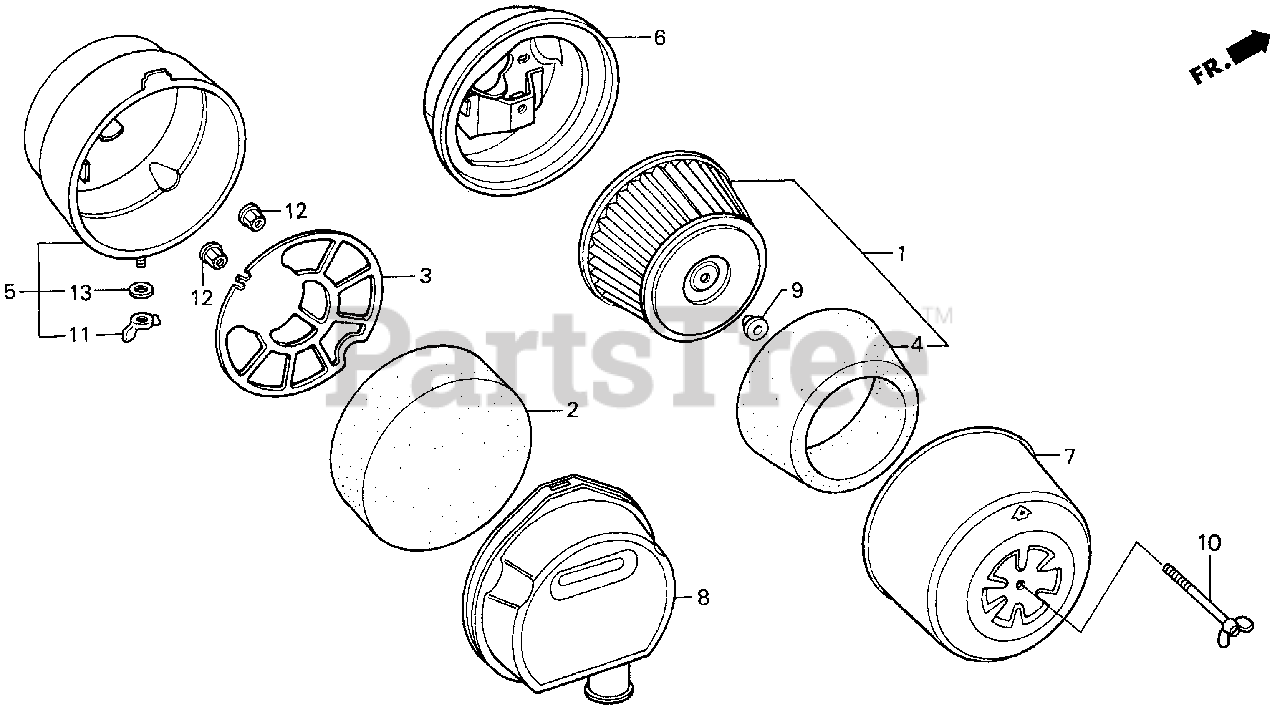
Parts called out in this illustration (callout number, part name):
1	ELEMENT, AIR CLEANER
2	ELEMENT, AIR CLEANER
3	GRID, AIR CLEANER
4	ELEMENT B, AIR CLEANER
5	HOUSING, AIR CLEANER (NOT AVAILABLE)
6	HOUSING, AIR CLEANER
7	COVER, AIR CLEANER (NOT AVAILABLE)
8	COVER, AIR CLEANER (NOT AVAILABLE)
9	GROMMET, AIR CLEANER
10	BOLT, AIR CLEANER COVER
11	WINGNUT, TOOL BOX SETTING
12	NUT, FLANGE (6MM)
13	WASHER, PLAIN (6MM)
